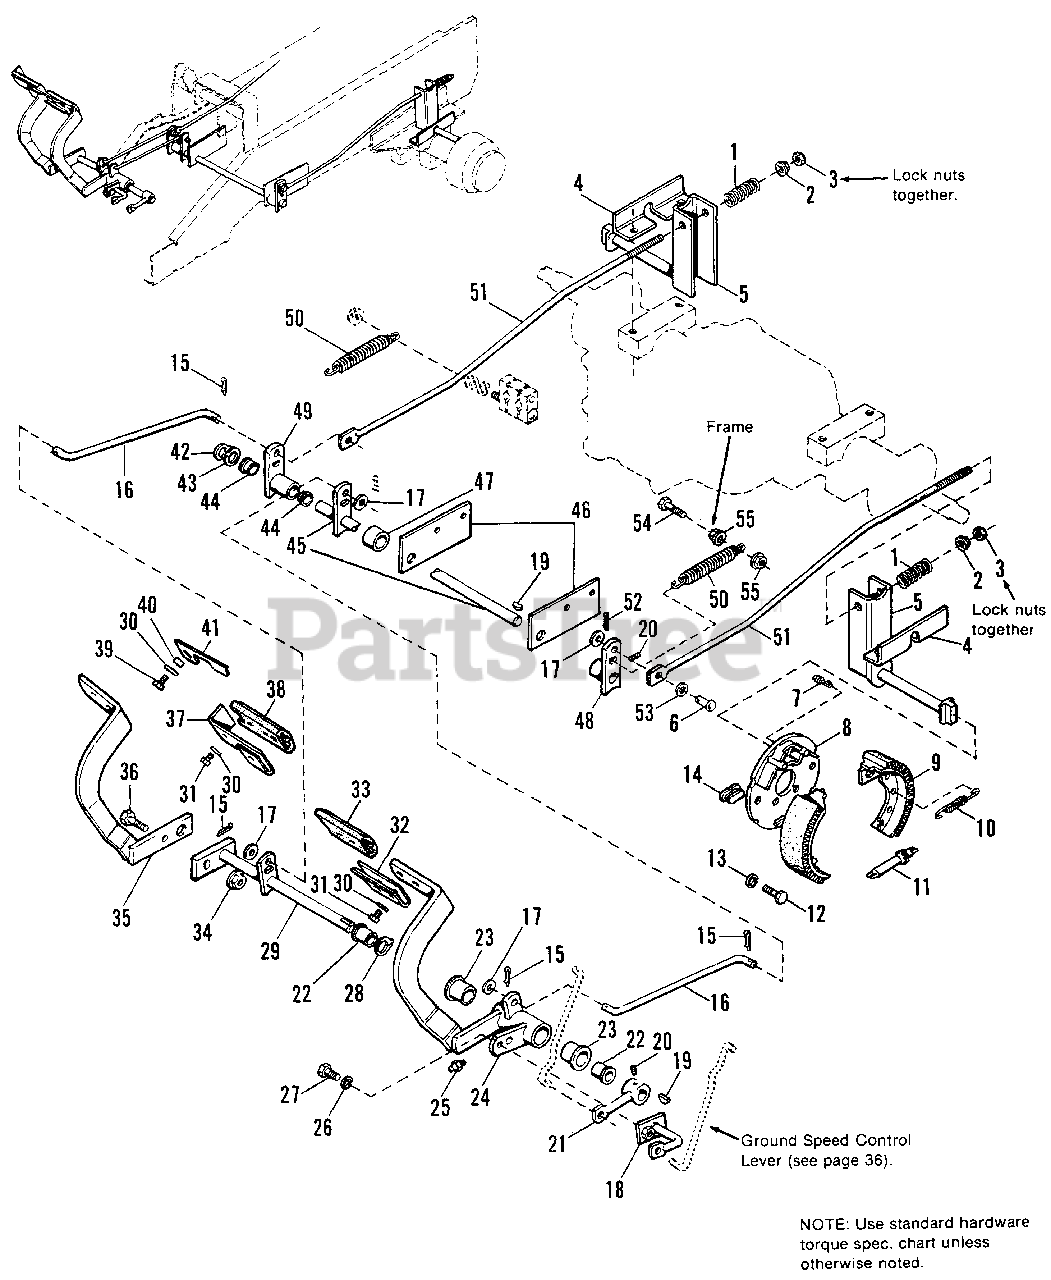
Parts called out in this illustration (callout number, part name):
1	SPRING, Compression
2	NUT, Large Flange, 1/2-13
3	NUT, Hex, 1/2-13
4	SUPPORT, Actuator
5	ACTUATOR ASSY.
7	SPRING, Extension
8	BRAKE SUPPORT ASSY.
9	BRAKE SHOE & PAD ASSY.
10	SPRING, Extension
11	SCREW ASSY., Brake Adjusting
12	CAPSCREW, Hex Hd., 3/8-16 x 1
13	LOCKWASHER, 3/8
15	PIN, Cotter, 1/8-3/4
16	ROD 8 PLATE, Brake
17	WASHER, Plain,13/32 x 7/8 x 5/64
18	ROD ASSY., Lock
19	KEY, Woodruff #9
20	SETSCREW, Sq. Hd., 5/16-18 x 1/2
21	ROD ASSY., Pivot Plate
22	BUSHING, 3/4 x 7/8 x 1
23	BUSHING, 1-1/4 x 1-3/4 x 1
24	LEVER ASSY., Brake, L.H.
25	FITTING, Lube, 1/4" Drive
26	LOCKWASHER, 5/16
27	CAPSCREW, Hex Hd.
28	RING, Retaining
29	SHAFT ASSY., Brake, R.H.
30	LOCKWASHER, 1/4
31	CAPSCREW, Hex Hd., 1/4-20 x 3/4
32	SUPPORT, Lock
33	PAD, Pedal, Inner
34	LOCKNUT, Hex, Whiz, 7/16-14
35	LEVER ASSY., Brake, R.H.
36	CAPSCREW, Hex Hd., 7/16-14 x 1-1/4
37	SUPPORT, Pedal Lock
39	CAPSCREW, Hex Hd., 1/4-20 x 1
41	LOCK, Pedal
42	RING, Retaining
43	WASHER, Plain, 3/4
45	SHAFT 8 LEVER ASSY., Brake Pivot
46	SUPPORT, Brake Cross Shaft
47	SPACER, Special
48	LEVER ASSY., Brake
49	LEVER ASSY., Brake
50	SPRING, Extension
51	ROD ASSY., (Incl. Ref. Nos. 6 & 53)
52	PIN, Cotter, 3/32 x 3/4
53	WASHER, 13/32
54	CAPSCREW, Hex, 5/16-18 x 1-1/4
55	NUT, Hex Flangelock, 5/16-18
